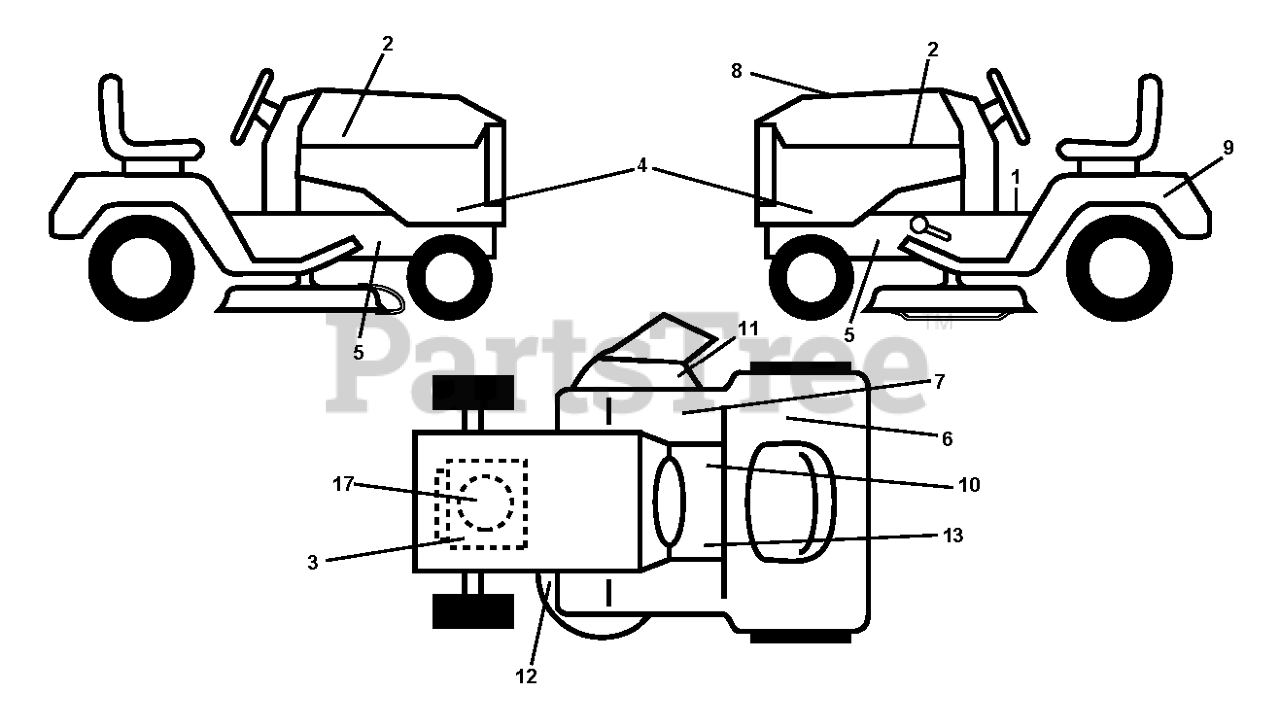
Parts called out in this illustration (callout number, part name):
1	LABEL
2	RP.DECAL.BADGE.170MM.TEXTLOGO
3	DECAL
6	Decal, Fender 100 DB/CE
7	DECAL
9	DECAL BTRY SYMBOLS
10	DECAL PARK BRAKE
11	DECAL, WARN. DEFLECT/CTFGR
12	Decal, Mower V-Belt Schematic
13	DECAL
17	Decal, BS Engine
